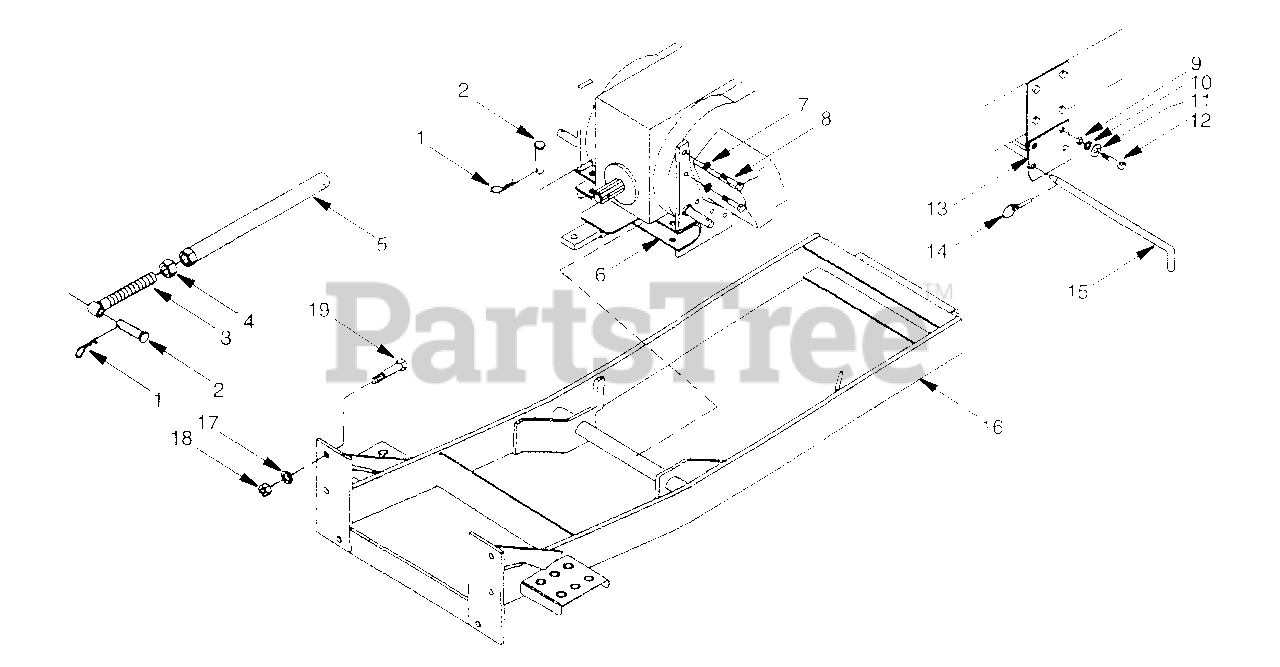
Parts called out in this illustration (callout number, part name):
1	Hairpin Cotter, 5/32
2	Clevis Pin, 3/4 x 17.75
3	Inner Top Link Assy
4	Hex Nut, 1
5	Outer Link Assy, 19.5
6	Rear Mounting Bracket Assy
7	Lockwasher, 9/16
8	Hex Hd Cap Screw, 10mm x 1.25P x 65mm
9	Locknut, 1/2
10	Lockwasher, 1/2
11	Washer, 1/2
12	Hex Hd Cap Screw, 1/2 NC x 1 1/2
13	Front Mounting Bracket Assy
14	Klik Pin, 1/4 x 1 3/4
15	Lock Pin, 3/4 x 17.75
16	Subframe Assy, 24.4 x 7
17	Lockwasher, 3/4
18	Nut, 3/4 NC
19	Hex Hd Cap Screw, 3/4 NC x 2
